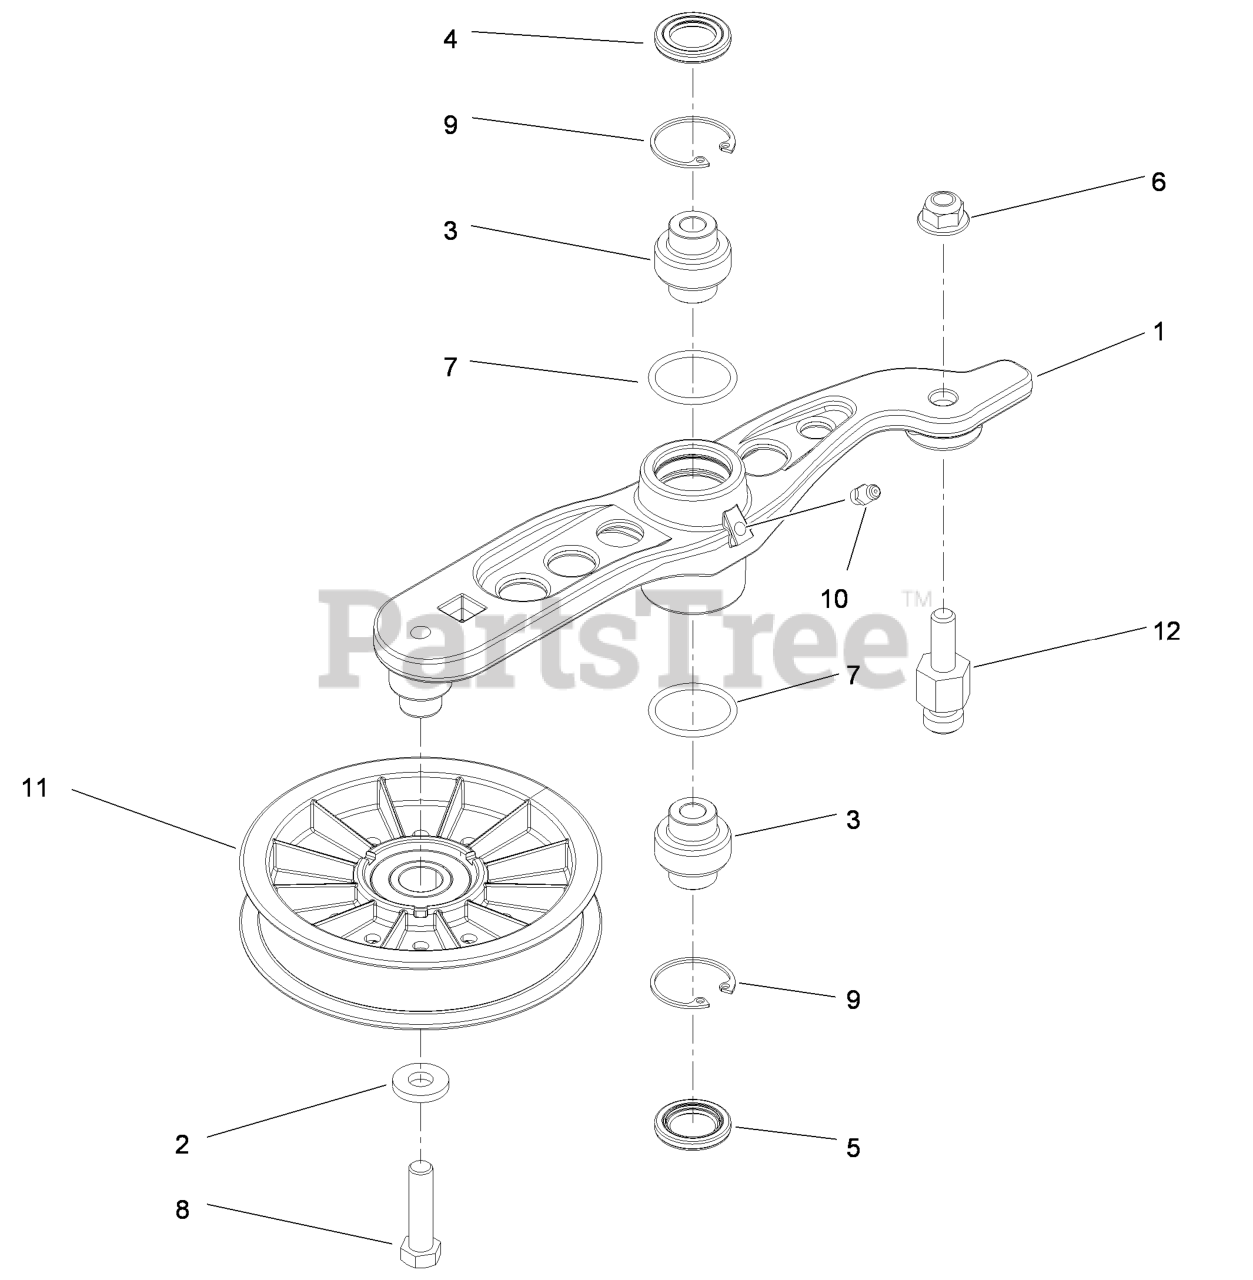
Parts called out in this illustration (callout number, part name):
1	Arm-Pump, Idler
3	BEARING-SPHERICAL
4	SEAL-LIP, DOUBLE
5	SEAL-LIP, SINGLE
6	Nut-Nyloc 3/8-16 Flg
8	SCREW-HH
9	RING-SNAP
10	FITTING-GREASE
11	PULLEY-IDLER
